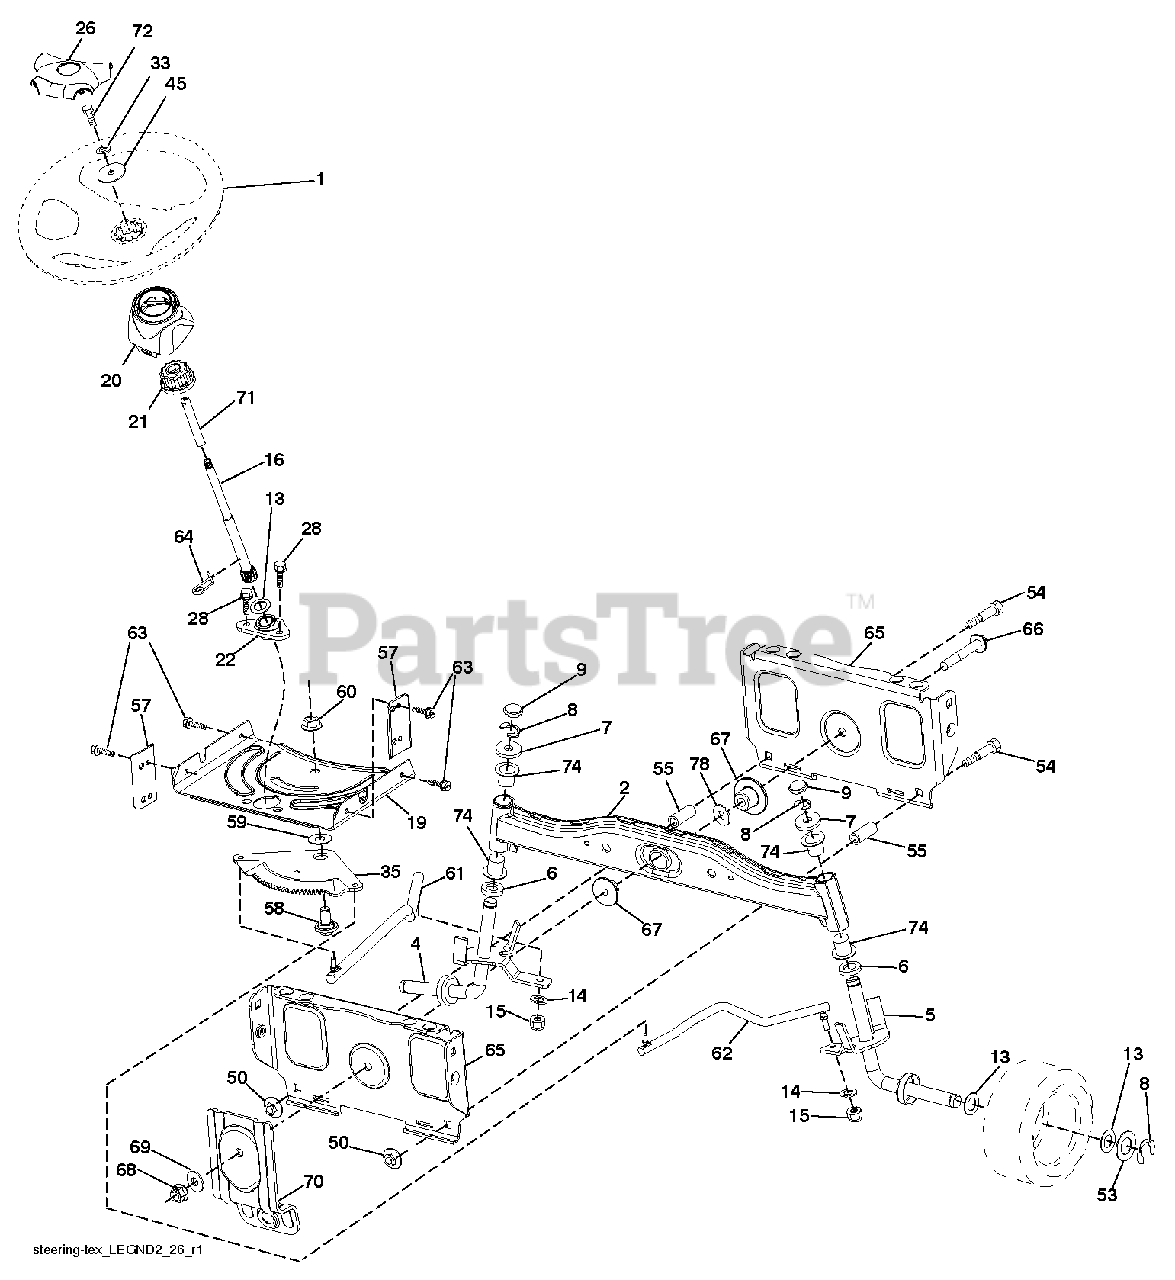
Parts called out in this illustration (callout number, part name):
1	Wheel, Steering
2	Axle Asm., Front
4	Spindle Asm., LH
5	Spindle Asm., RH
6	Bearing, Race Thrust Harden
7	Washer 25/32 x 1-5/8 x 16 Ga.
8	Ring, Clip #T5304-75
9	Cap, Spindle
13	Washer 25/32 x 1-1/4 x 16 Ga.
14	Washer Lock 3/8
15	Nut, Crown Lock 3/8-24 unf
16	Shaft Steering
19	Plate Steering
20	Boot, Steering
21	Adapter, Wheel Steering
22	Bushing, Strg. Blk
26	Insert, Wheel Steering
28	Screw 3/8-16 x 3/4
33	Washer Lock 5/16
35	Gear, Sector Plate
45	Washer 11/32 x 2-3/8 x 12 Ga.
50	Nut Lock Flg 3/8-16 unc
53	Washer Hardened .793 x 1.637 x .060
54	Bolt Hex HS 3/8-16 unc x 2-1/4
55	Spacer Brace Axle
57	Bracket Upstop
58	Bolt Shoulder Sector Pivot CFM
59	Washer Thrust Sector Steering
60	Nut Flange Lock 5/8-11
61	Draglink, LH
62	Draglink, RH
63	Screw 5/16-18 x 3/4
64	Retainer Clip Spring Steering
65	Brace Axle Front
66	Bolt Hex Fghd 7/16-14 x 3 Serr
67	Bushing PM Front Axle
68	Nut Lock Flange 7/16-14 Gr. 5
69	Washer 1.5 x .505 x .118
70	Bracket Deck Susp. Front
71	Shaft Ext. Steering
72	Bolt 5/16-18 x 4.5 Gr. 5
74	Bearing
78	Washer Thrust .515 x .750 x .033
